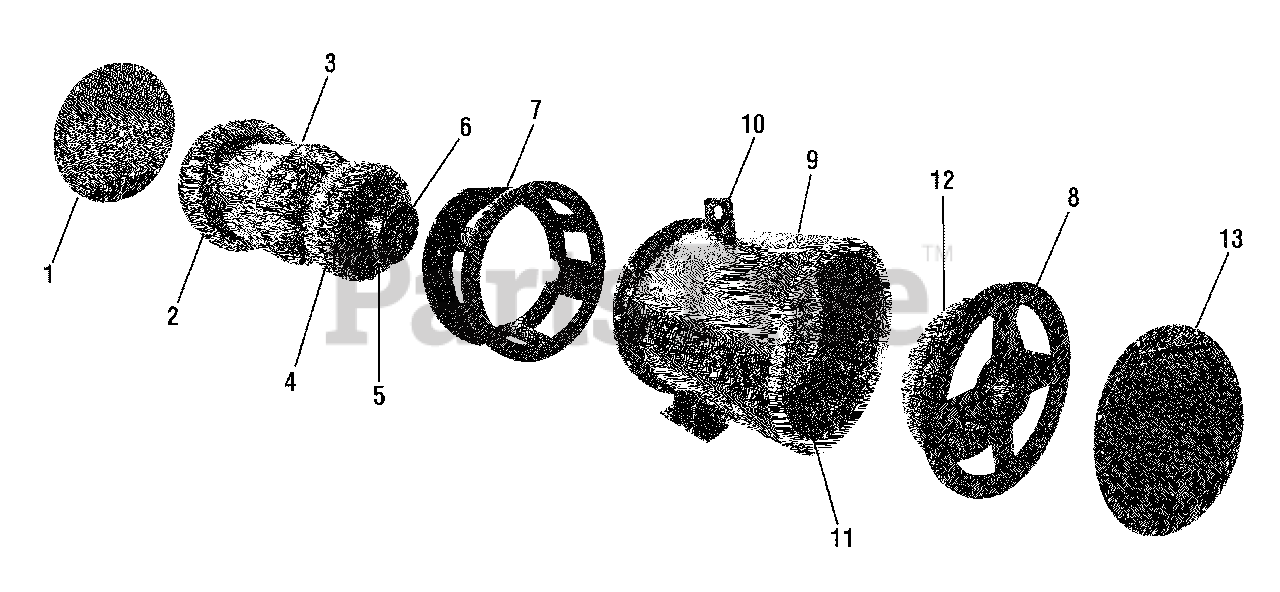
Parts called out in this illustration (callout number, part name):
1	DISC-COUPLING
2	FAN
3	ROTOR
5	RECTIFIER ASSEMBLY RING
7	HOUSING-BELL
8	BEARING SUPPORT
9	HOUSING-GENERATOR
10	LIFTING EYE
11	STATOR
13	COVER
